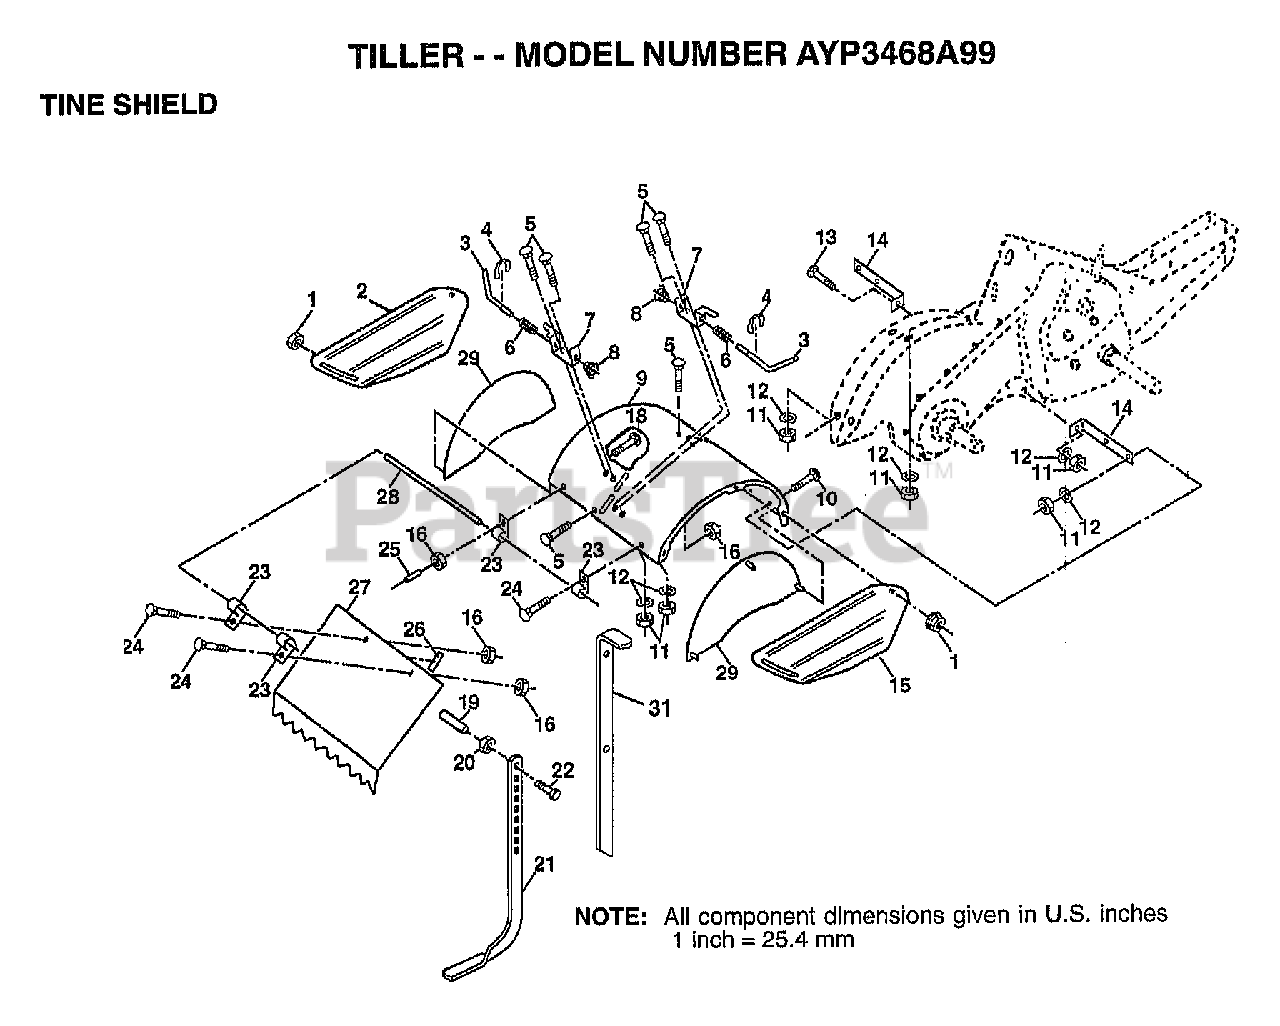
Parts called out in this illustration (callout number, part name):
1	NUT
3	STAKE PIN TI
4	KLIP RING TI
5	BOLT
6	SPRING TI
7	LATCH BRACKET TI
8	SPRING CRT
10	BOLT
11	LOCKWASHER
12	NUT.HEX.5/16-18
13	BOLT
14	BRKT SHIELD TINE
16	NUT
18	BOLT
19	GRIP CRT
20	NUT.HEX.3/8-16UNC
22	BOLT
23	HINGE CRT
24	BOLT
25	VINYL CAP TI
26	PAD IDLER TI
28	PIN HINGE
31	"STAKE,DRAG"
